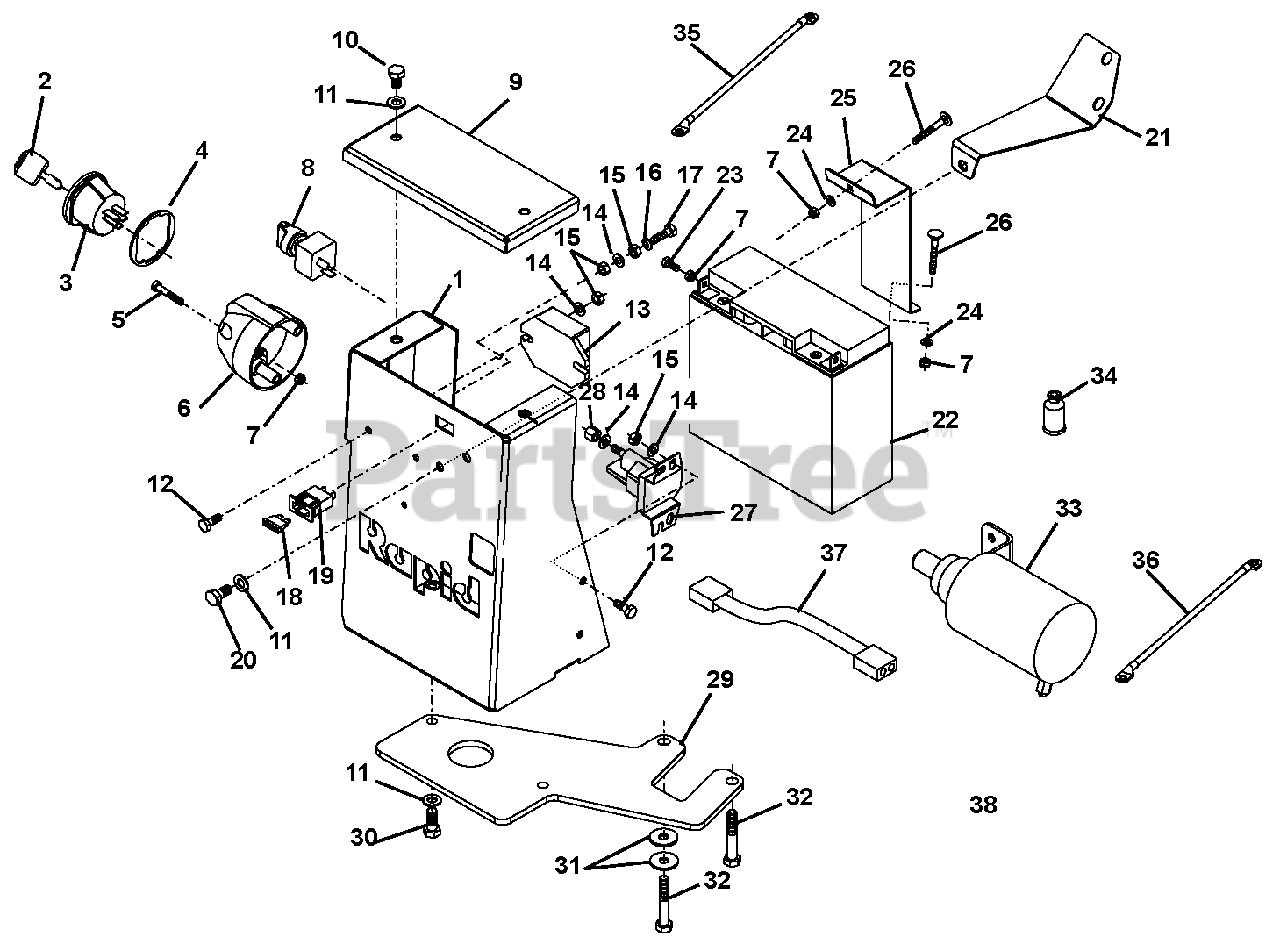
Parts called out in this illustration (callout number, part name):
1	Battery Container
2	Assembly, Key
3	Assembly, Starter Switch
5	Screw, Cylindrical Head
6	Plug, Socket
7	Nut, Lock M5
8	Switch, Rotary
10	Bolt, Hex D933 M8 x 12
11	Washer, Form S 8.2/16.2 x 1.4
12	Bolt, Hex M6 x 16
13	Regulator
15	Nut, Hex M6
16	Washer, Lock M6
17	Bolt, Hex M6 x 20
18	15A, Fuse
19	Fuse Box
20	Bolt, Hex M8 x 16
22	Battery, Rapid
23	Bolt, D933 M5 x 12
24	Washer, 5.3 x 10 x 1
25	Bolt, Fastener
26	Screw, Truss Head, D603 M5 x 40
28	Nut, Hex UNC1/4"
29	Support, Battery
30	Bolt, Hex M8 x 20
31	Washer, 8.4 x 25 x 2
32	Bolt, Hex M8 x 50
33	Electrical Starter
34	Protecting Cap
35	Cable, Black
36	Cable, Red
38	Wiring Harness
